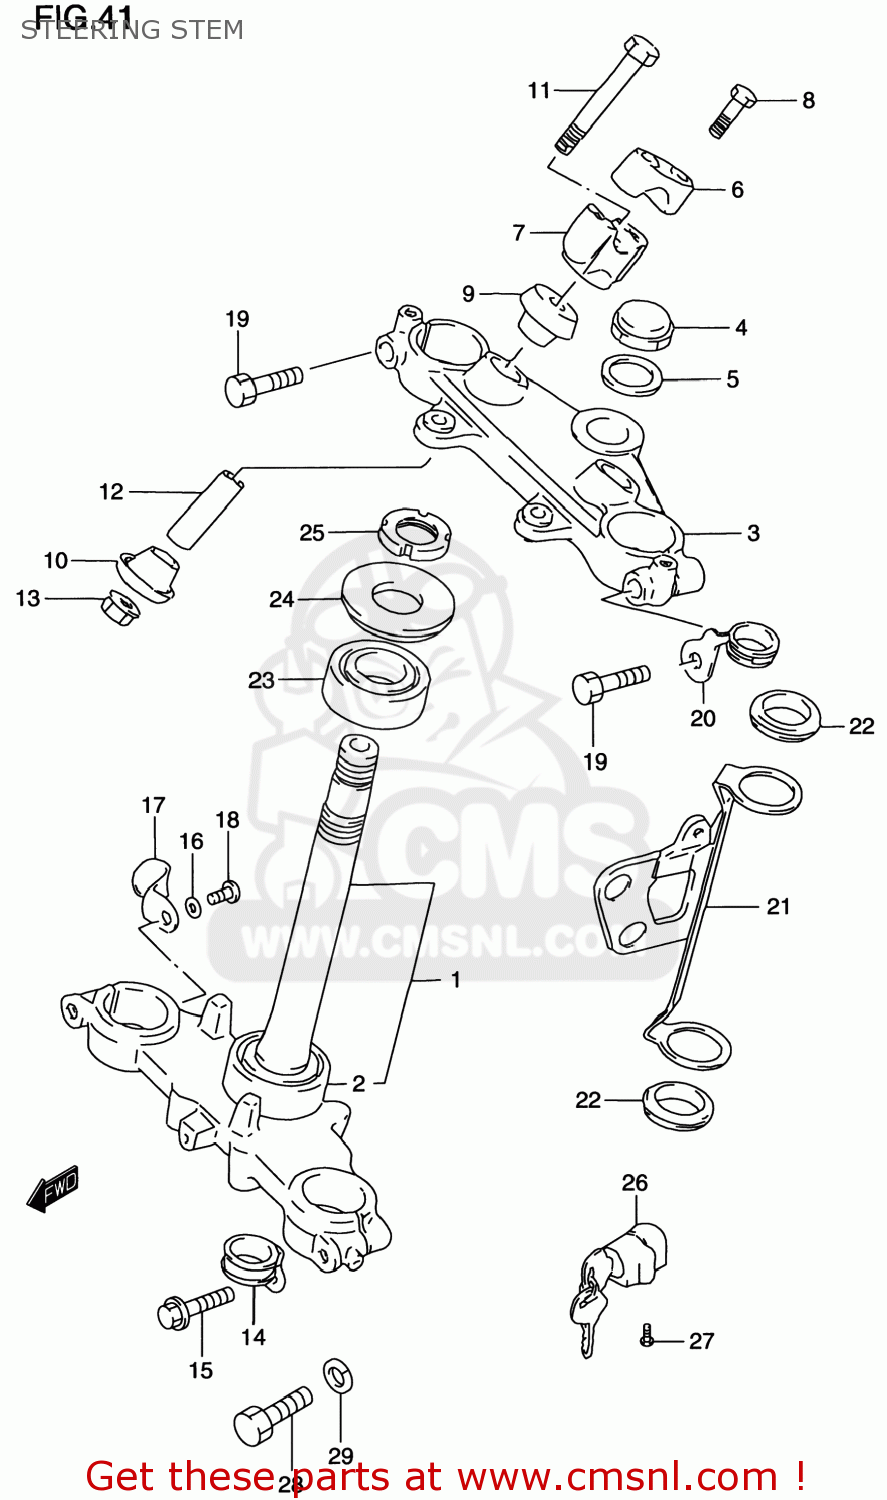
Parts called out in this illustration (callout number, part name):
1	STEM,STEERING
2	BEARING(30X55X17)
3	HEAD,STEERING STEM
4	NUT,CAP
5	WASHER
6	HOLDER,HANDLE UPR
7	HOLDER,HANDLEBAR LWR
8	BOLT
9	RUBBER,HANDLE HOLDER
10	CUSHION,RUBBER UNDER
11	BOLT,LWR HOLDER
12	SPACER
13	NUT
14	CLIP,LOWER
15	BOLT
16	WASHER,LOCK
17	CLIP
18	SCREW
19	BOLT
20	CLIP
21	BRACKET,HEADLAMP,R
22	CUSHION,HEADLAMP HSG BRACKET
23	BEARING(25X47X15)
24	SEAL,STEERING UPR DUST
25	NUT,STEERING
26	LOCK SET,STEERING
27	SCREW
28	BOLT,INNER TUBE FITTING
29	WASHER
